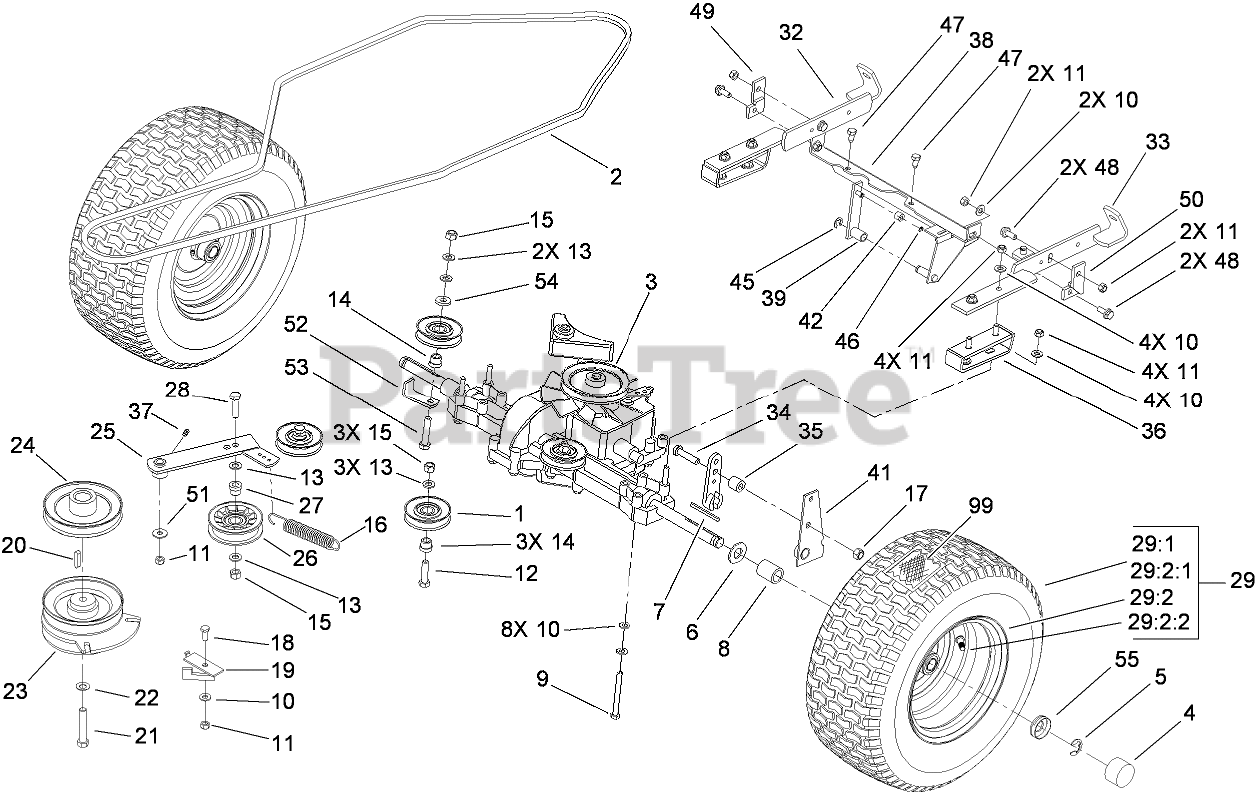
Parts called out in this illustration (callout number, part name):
1	PULLEY-IDLER
2	V-BELT-TRACTION
3	TRANSMISSION
4	CAP-HUB
5	CLIP-SPRING
6	WASHER
7	KEY-SQUARE
8	SPACER-AXLE
9	SCREW-HH
10	WASHER-PLAIN
11	NUT-LOCK, NI
12	SCREW-HH
13	WASHER-FLAT
14	BUSHING-IDLER
15	NUT-LOCK, NI
16	SPRING
17	NUT-LOCK, NI
18	SCREW-HH
19	RETAINER
20	KEY-SQUARE
21	SCREW-HH
22	WASHER-SPRING, BELLEVILLE
23	CLUTCH-ELECTRIC
24	PULLEY-ENGINE
25	ARM-IDLER
26	PULLEY-IDLER
27	BUSHING-IDLER
28	SCREW-HH
29	WHEEL AND TIRE ASM
29:1	TIRE
29:2	WHEEL ASM
29:2:2	Valve-Tire
32	Bracket-Right
33	Bracket-Left
34	SCREW-HH
35	SLEEVE
36	BRACKET-SUPPORT
37	FITTING-GREASE
38	Bar ASM
39	Arm-Switch
42	Roller
45	Stirrup
46	STIRRUP
47	SCREW-THREAD FORMING
48	SCREW-HEX
49	BRACKET-RIGHT
50	BRACKET-LEFT
51	WASHER-PLAIN
52	RETAINER-BELT
53	SCREW-HH
54	WASHER-FLAT
55	RETAINER-CAP, HUB
